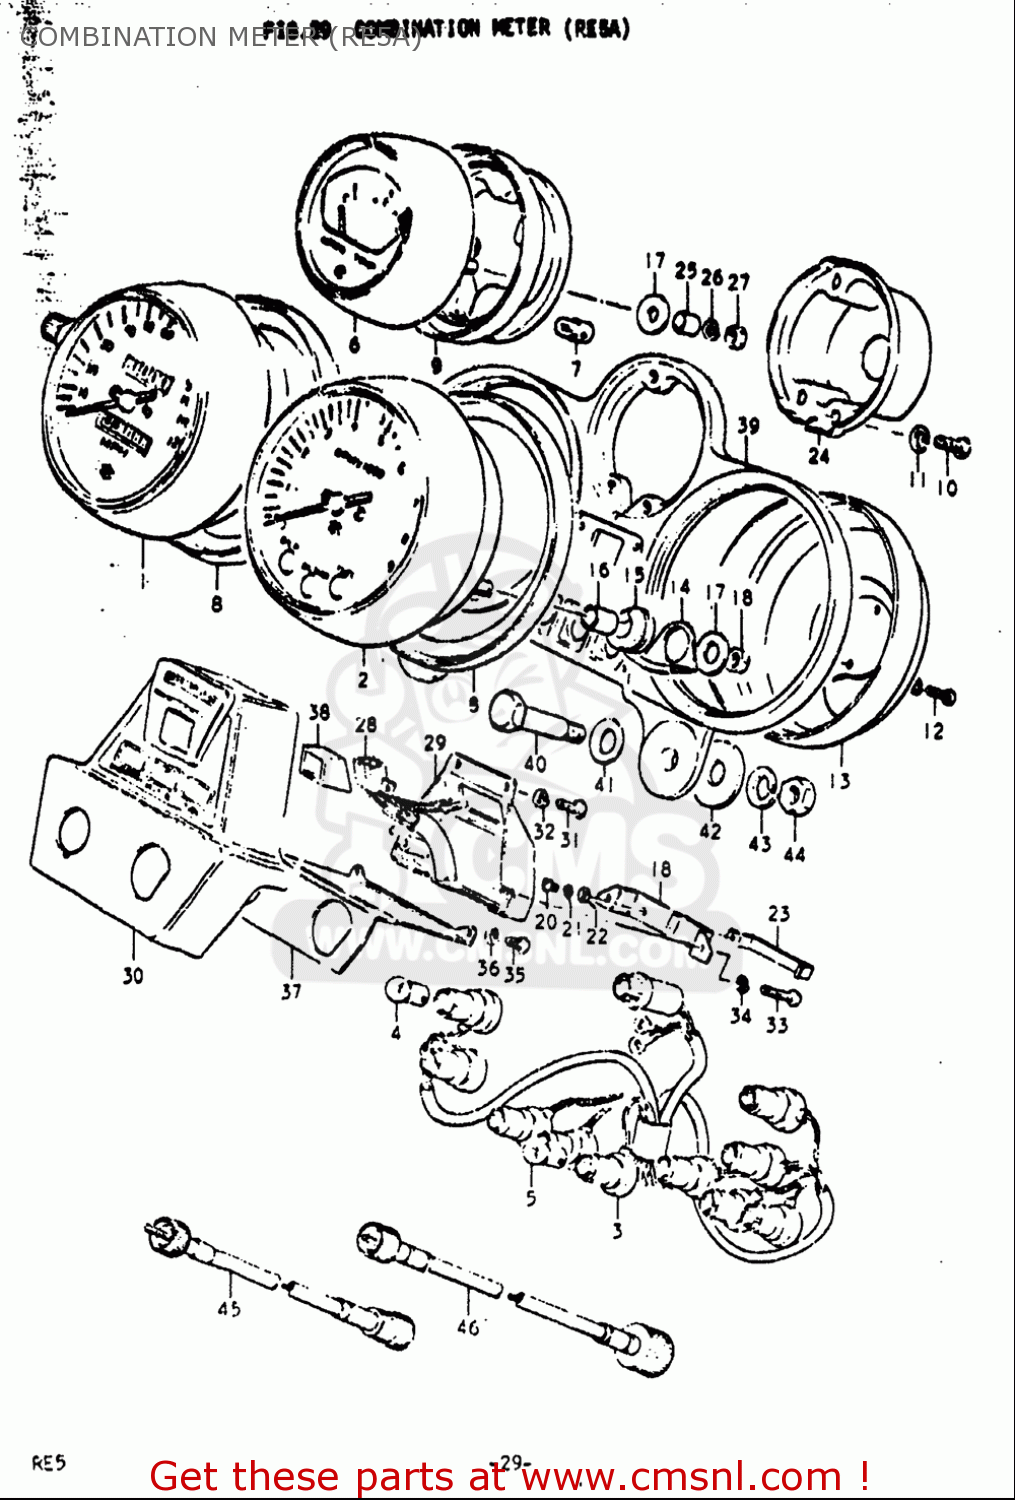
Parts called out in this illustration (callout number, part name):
4	BULB(12V3.4W,STANLEY,A72A)
5	BULB(12V1.7W,A71A)
7	BULB(12V2W,STANLEY,A1272J)
8	CUSHION,SPEEDOMETER
10	SCREW
11	WASHER,LOCK
12	SCREW
13	PLATE,UNDER
16	SPACER,METER
17	WASHER(5.5X16X1.2)
18	NUT
20	SCREW
21	WASHER,LOCK
22	WASHER
26	WASHER,LOCK
27	NUT
30	CASE,PILOT BULB
31	SCREW
32	WASHER,LOCK
34	WASHER,LOCK
35	SCREW 4X6
36	WASHER,LOCK
37	BRACKET (BB)
40	BOLT(8X39.2)
41	WASHER
42	WASHER(8.5X28X1.6)
43	WASHER,LOCK
44	NUT
45	CABLE ASSY,SPEEDOMETER
